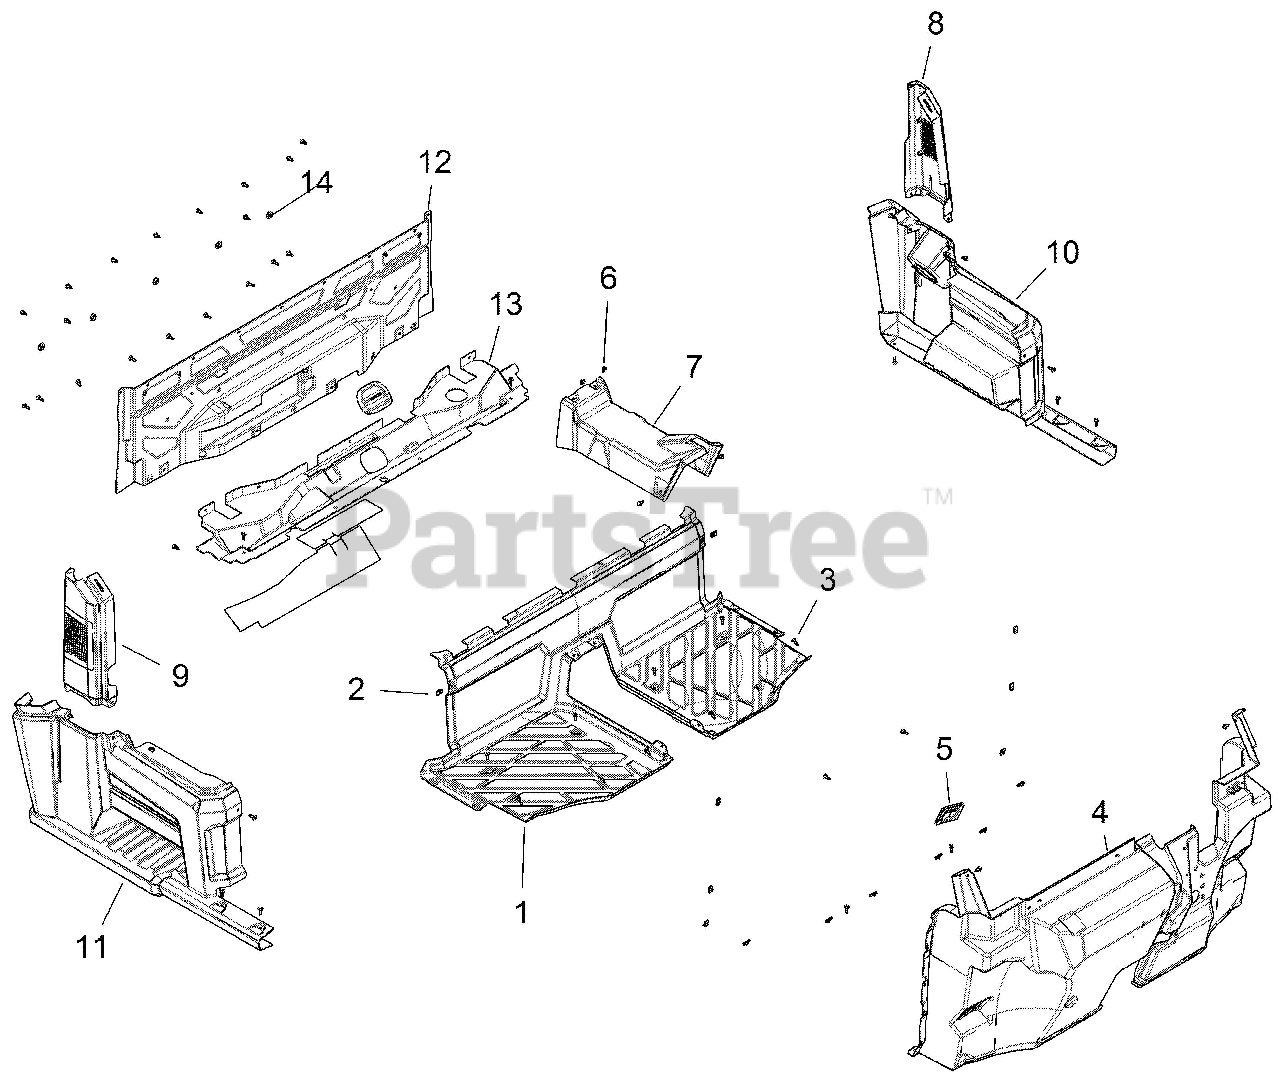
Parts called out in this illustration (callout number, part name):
1	FLOOR-BLK
2	CLIP-U SPEED NUT
3	SCR-TXTH-M6X1.0X25 RIE
4	FLOOR-FRONT,BLK
5	GROMMET-STEERING,FLOOR
6	RIVET-TUFLOK,.315-.325X.787 (5
7	COVER-DRIVE SHAFT,FLOOR,BLK
8	ASM-FENDER-REAR,UPPER,LH,BLK
9	ASM-FENDER-REAR,UPPER,RH,BLK
10	FENDER-REAR,W/ROCKER,LH,ARIENS
11	FENDER-REAR,W/ROCKER,RH,ARIENS
12	PANEL-CLOSEOFF,REAR,BLK
13	PANEL-CLOSEOFF,LOWER,BLK
14	PLUG-COMPARTMENT
